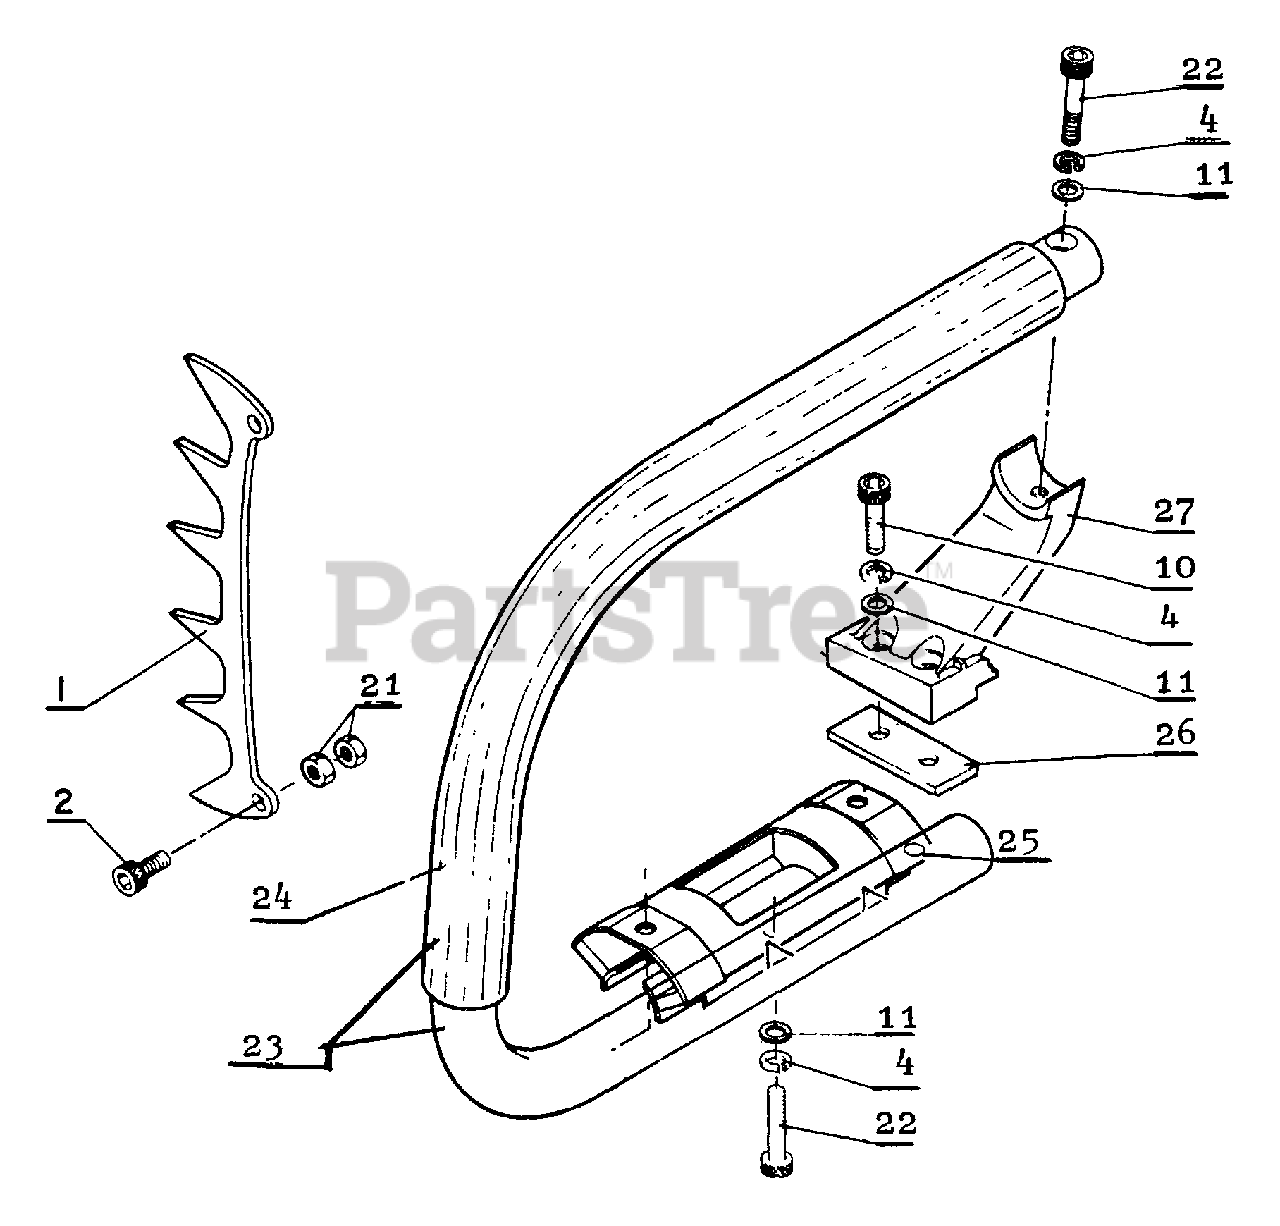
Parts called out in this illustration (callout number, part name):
1	BUMPER, SPIKED
2	SCREW - 5×15
4	WASHER, SPRING 5
10	BOLT 5×20
11	WASHER
21	LOCKNUT - 5
22	BOLT 5×25
23	HANDLE - FRONT
24	HANDLE, FRONT
25	ADAPTOR, CRANKCASE
26	RUBBER CUSHION, FRONT HANDLE
27	HANDLE, SUPPORT
